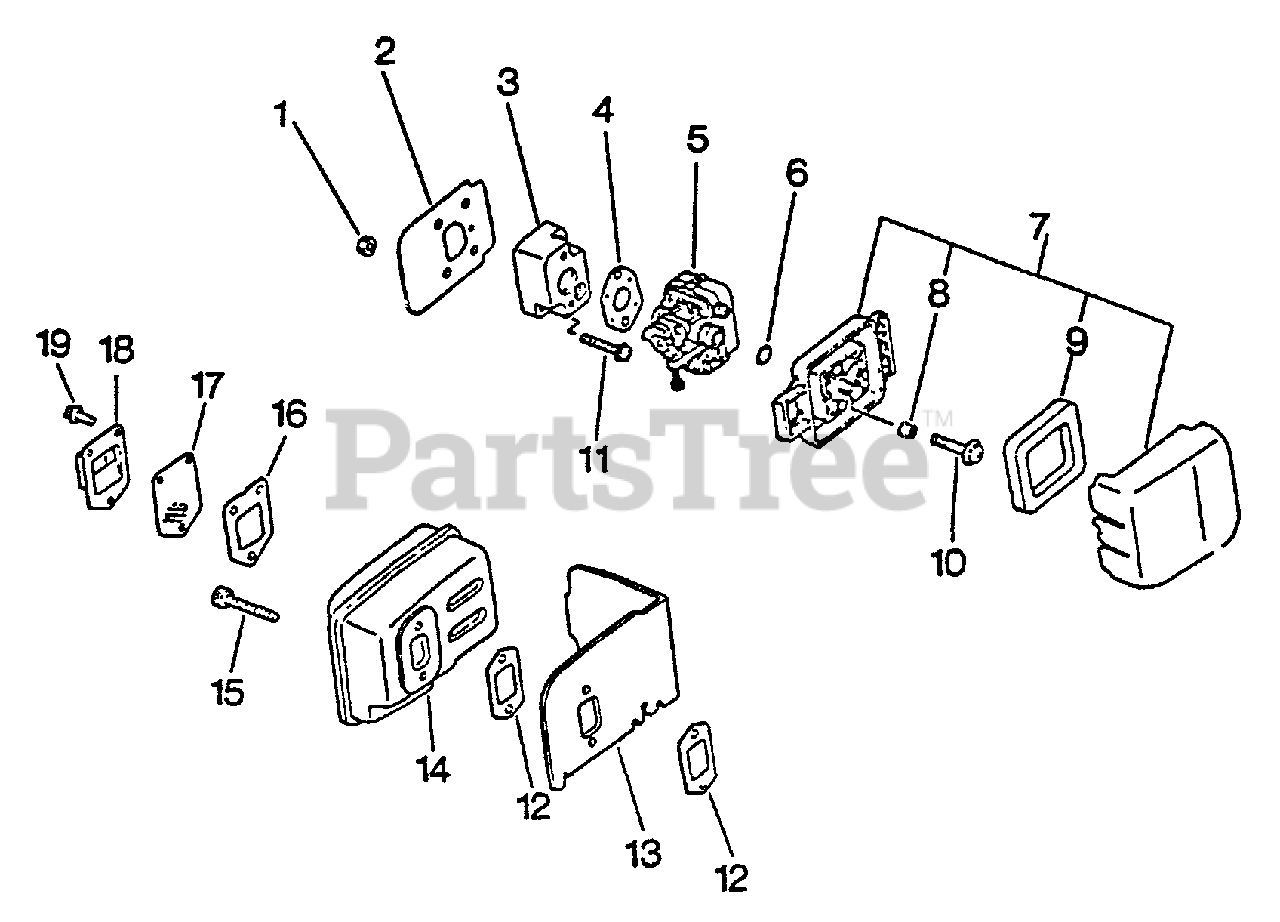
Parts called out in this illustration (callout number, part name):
2	SHIELD, INTAKE
3	INSULATOR, INTAKE
4	GASKET, INTAKE
5	CARBURETOR WYL-7
6	O-RING - 15
7	AIR CLEANER ASSY
8	SLEEVE
9	FILTER, AIR
10	SCREW - 5X64
11	SCREW - 5X22
12	GASKET, EXHAUST
13	COVER, EXHAUST
14	MUFFLER
15	SCREW - 5X55
16	GASKET, EXHAUST
17	SCREEN, SPARK ARRESTOR
18	GUIDE, EXHAUST
19	SCREW - 4X10
